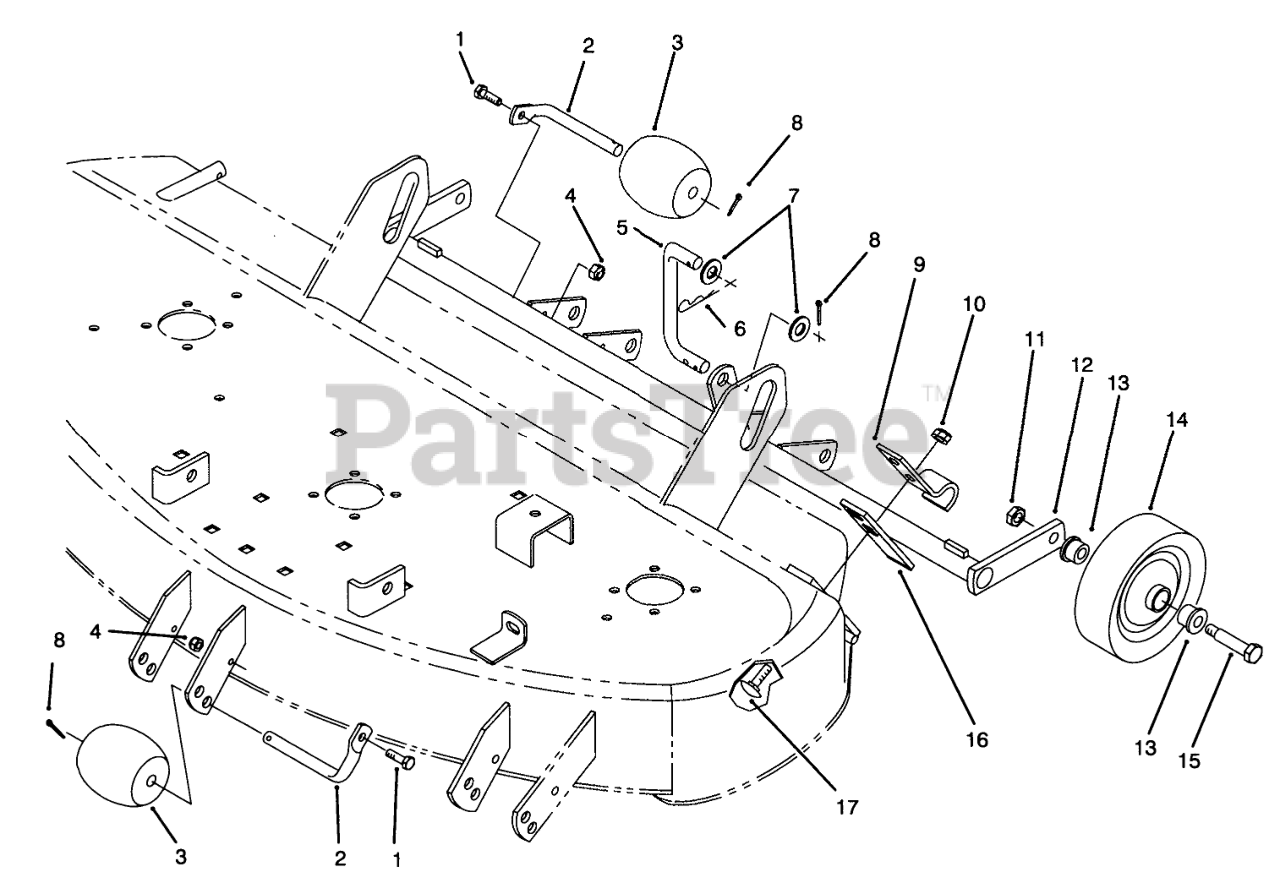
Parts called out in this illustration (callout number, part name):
1	Capscrew
2	SHAFT-ROLLER
3	ROLLER
4	NUT-LOCK, NI
5	LINK-REAR
6	Pin-Cotter
7	WASHER-FLAT
8	PIN-COTTER
9	Clamp
10	NUT-LOCK, NI
11	NUT-HEX
12	Support-Gage Wheel
13	BEARING
14	Assembly-Wheel (Incl. Ref.# 13)
15	BOLT-SHOULDER
16	Bar
17	SCREW-CARR
